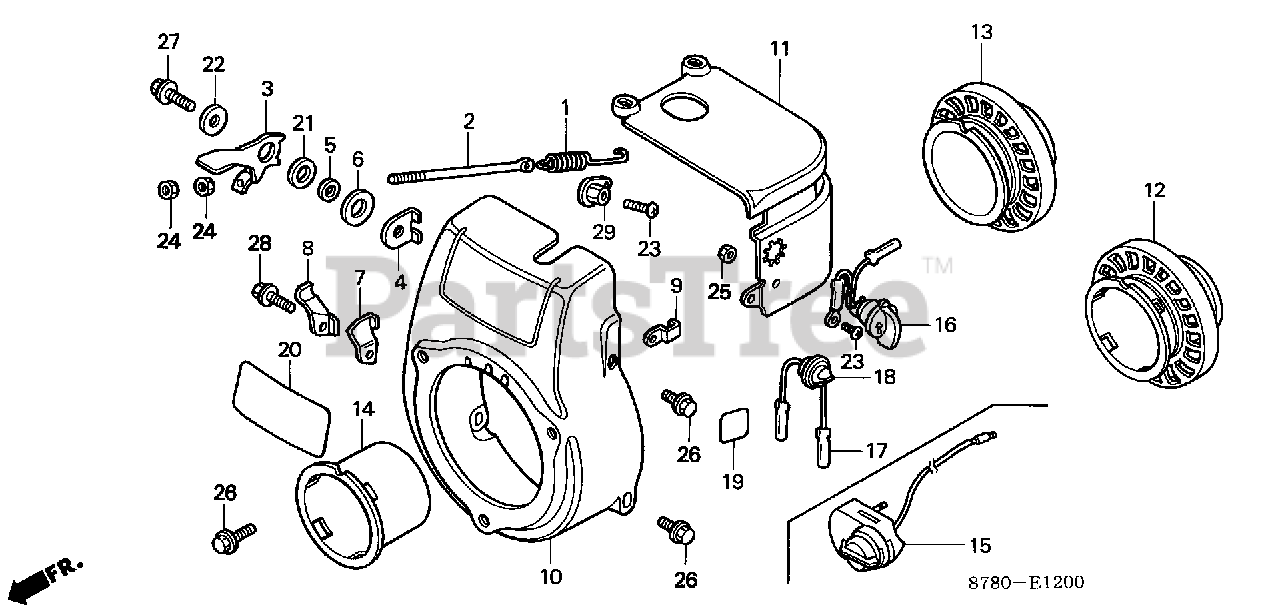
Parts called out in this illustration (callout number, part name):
1	SPRING, GOVERNOR (NOT AVAILABLE)
2	ROD, ADJUSTING (NOT AVAILABLE)
3	LEVER, CONTROL
4	STOPPER, LEVER
5	SPACER, LEVER
6	SPRING, LEVER
7	STAY A, THROTTLE WIRE
8	STAY B, THROTTLE WIRE
10	COVER, FAN (NOT AVAILABLE)
11	COVER, SIDE
12	PULLEY, STARTER (NOT AVAILABLE)
13	PULLEY, STARTER
14	PULLEY, STARTER
14	PULLEY, STARTER (NOT AVAILABLE)
16	SWITCH ASSY., ENGINE STOP
17	WIRE A, ENGINE SWITCH
18	GROMMET, SIDE COVER (NOT AVAILABLE)
20	PLATE, DESCRIPTION
21	WASHER, THROTTLE LEVER (NOT AVAILABLE)
22	WASHER (6.5X20)
23	SCREW, PAN (5X8)
24	NUT, HEX. (4MM)
25	NUT, HEX. (5MM)
26	BOLT, FLANGE (6X12)
27	BOLT, FLANGE (6X16)
28	BOLT, FLANGE (6X12)
